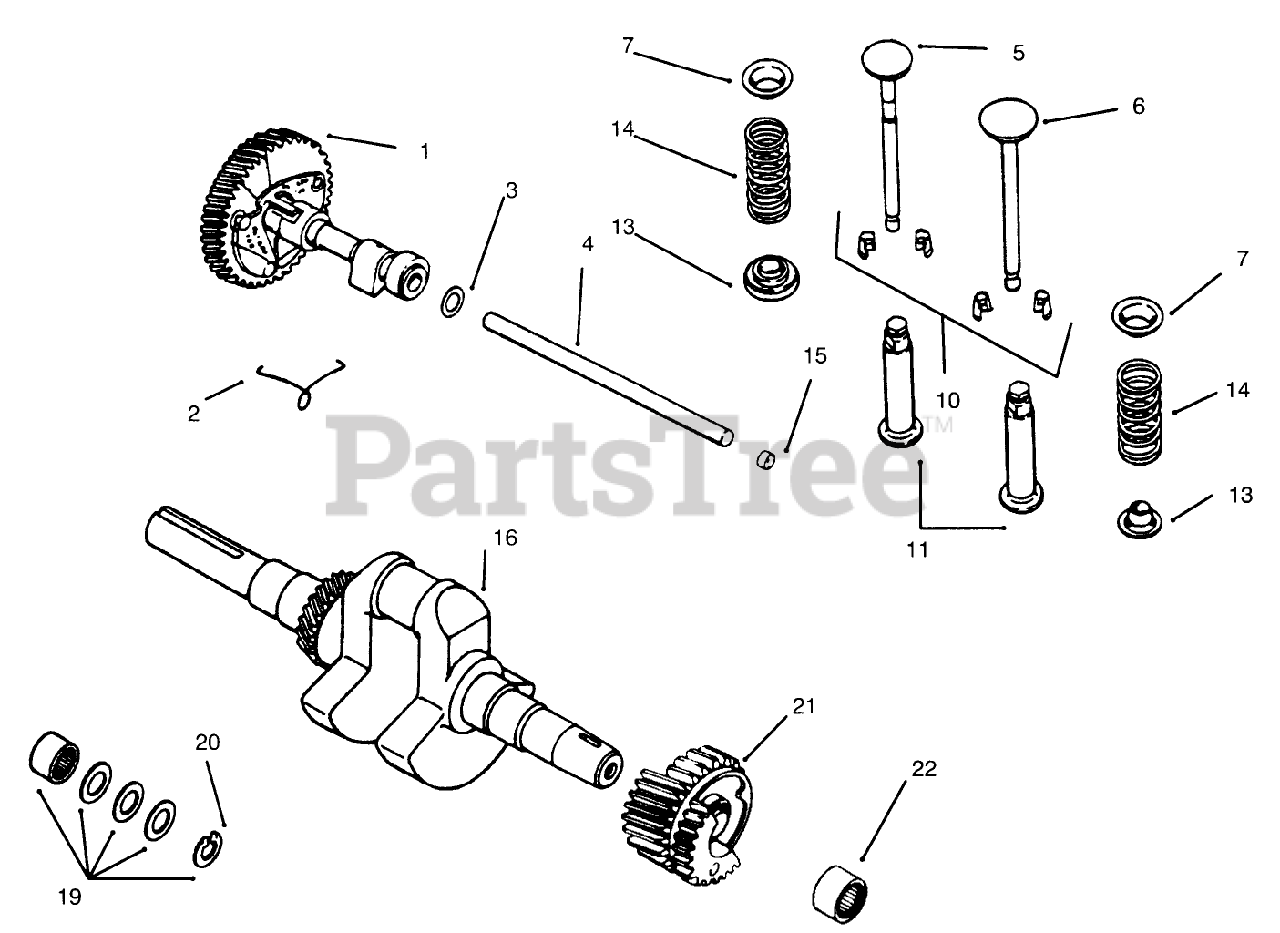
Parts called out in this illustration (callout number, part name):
1	Camshaft ASM INC 2
2	Spring
3	Spacer
4	Pin-Camshaft
5	Valve exhaust
6	Valve-Intake
7	Retainer-Spring
8	Spring
10	Kit-Retainer
12	Tappet
13	Rotator-Valve
14	Spring
15	Plug
16	Kit-Crankshaft
19	Kit-Spacer
20	Retainer
